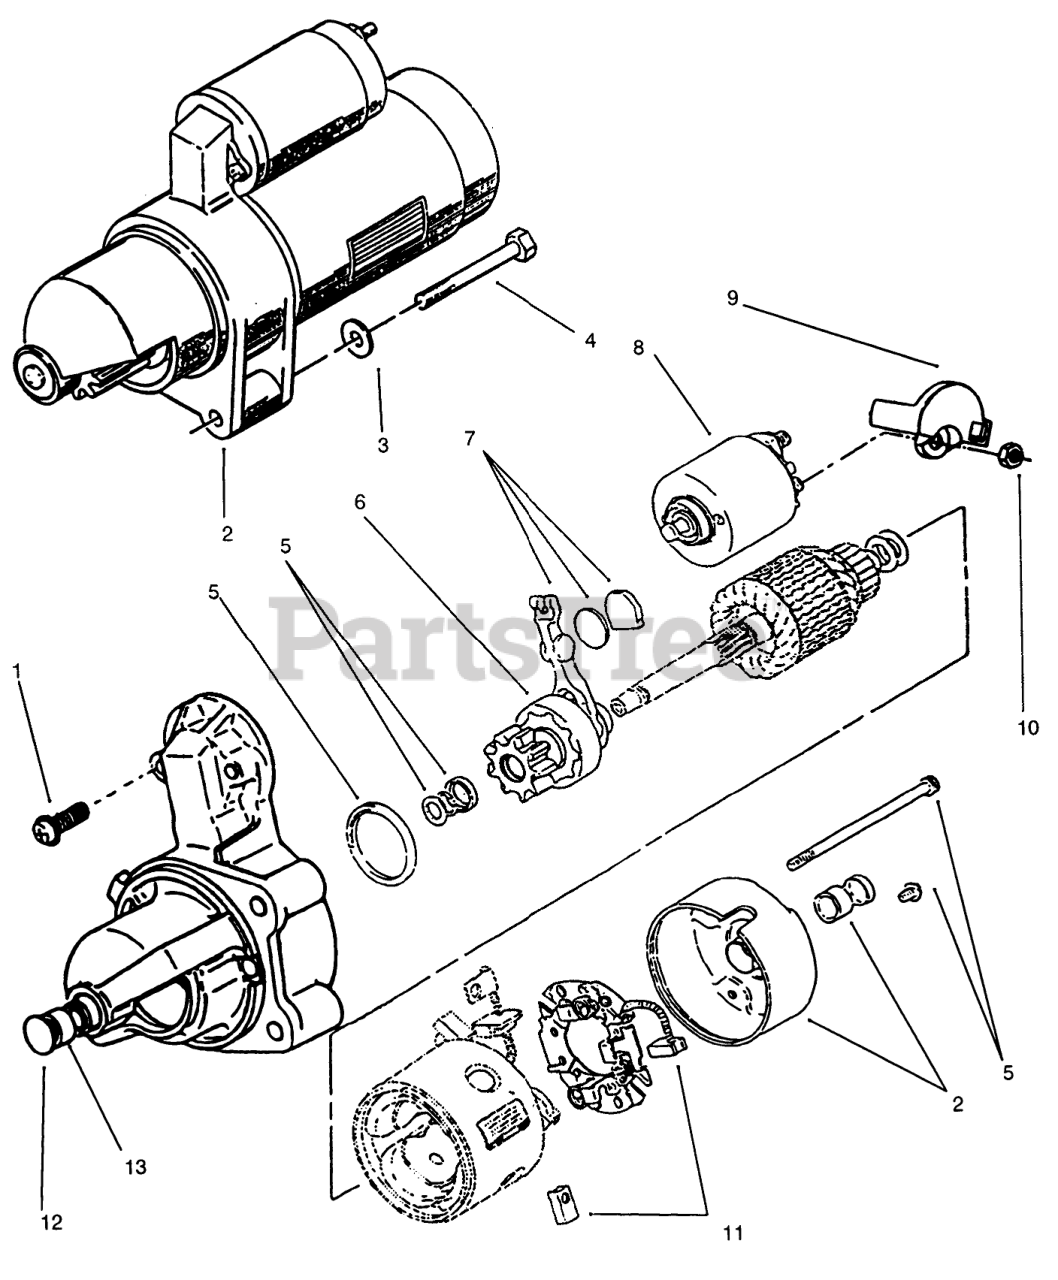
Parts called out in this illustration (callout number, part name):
1	Starter Hdwr Kit (Includes Solenoid Screws 2], Brush Holder Screws 2], Thru Bolts 2], Armature Shims 2], Pinion Stop Collar, & Pinion Retaining Ring)
2	STARTER
3	WASHER
4	SCREW
5	DUST-SEAL KIT
6	Clutch-Starter (Includes Pinion Gear w/Clutch)
7	Kit-Starter Shift Lever (Includes Shift Lever, Wear Plate & Rubber Plug)
8	Kit-Starter Solenoid (Includes Solenoid, Spring, & Plunger)
9	Cap-Starter Solenoid
10	Nut
11	Kit-Starter Brush (Includes Positive Brush 2] & Negative Brush w/Pigtail)
12	Kit-Bushing (Includes Front Bushing & Rear Cap w/Bushing)
13	Holder-Starter Brush (Includes Brush Holder w/Negative Brush)
